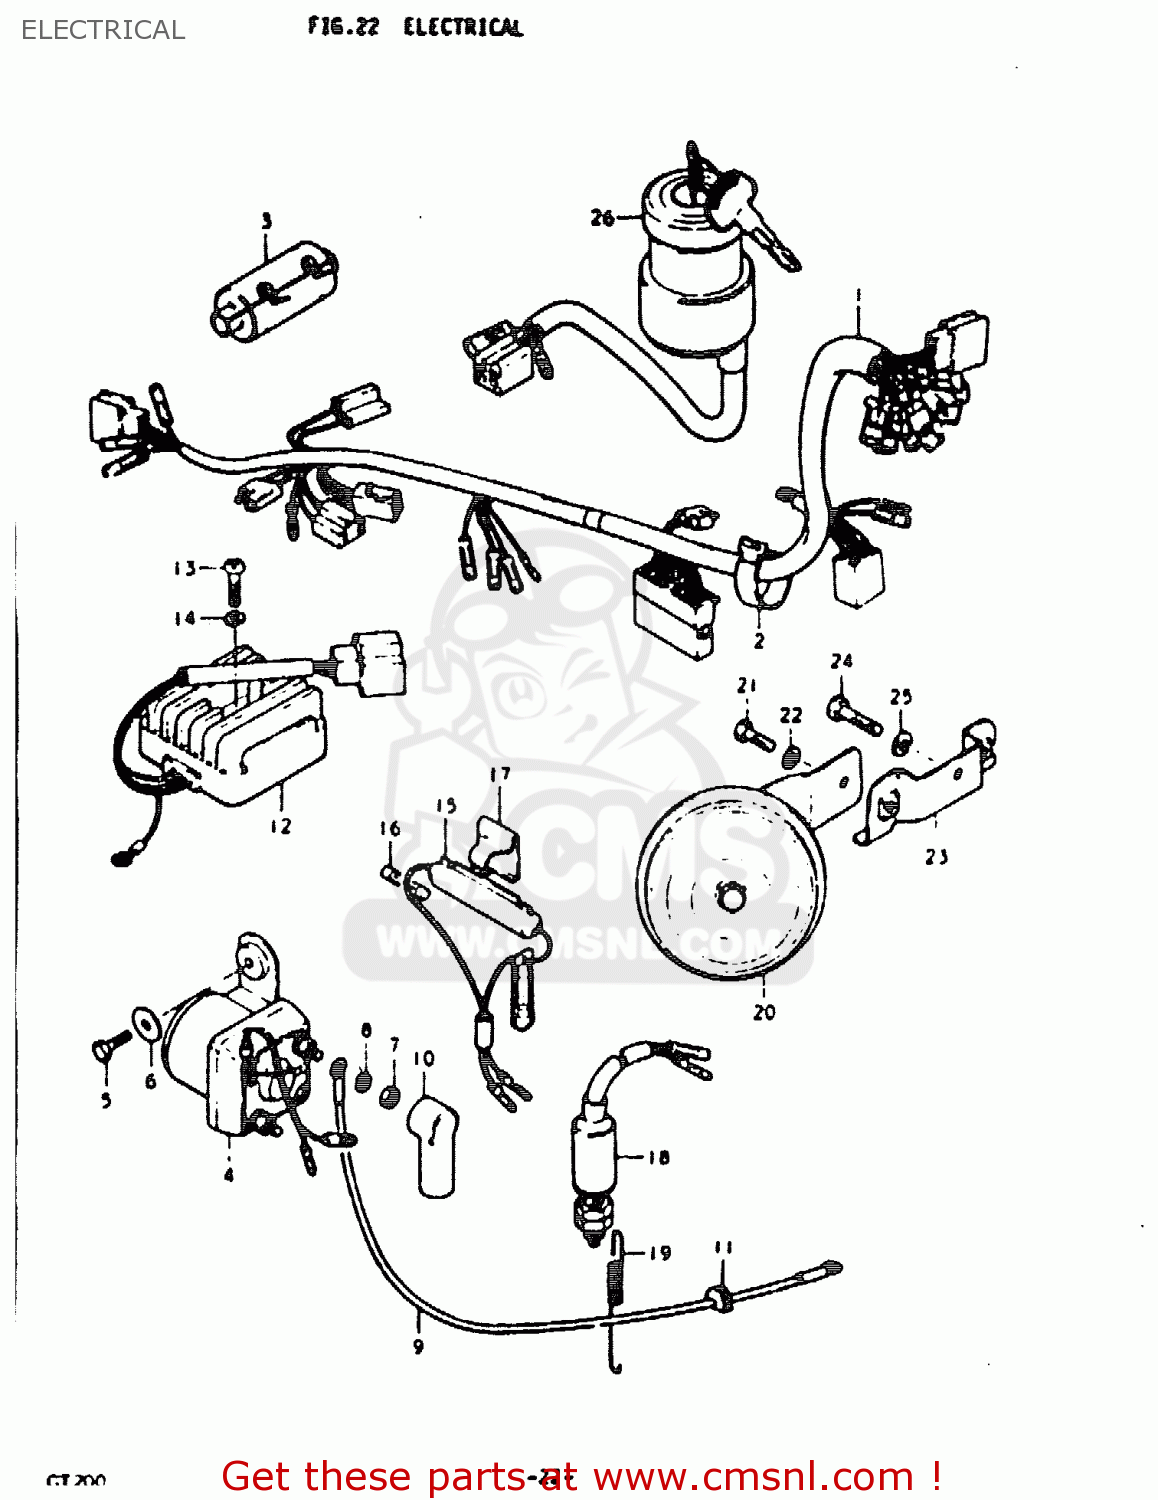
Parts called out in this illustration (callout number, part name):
1	WIRING HARNESS
2	CLAMP
3	BOOT,WIRING HARNESS
4	RELAY,STARTER SWITCH
5	BOLT, UPPER
6	WASHER
7	NUT 6MM
8	LOCK WASHER
9	WIRE,STARTER MOTOR LEAD
10	CAP,STARTER RELAY
11	GROMET
12	RECTIFIER ASSY,REGULATOR
13	SCREW
14	LOCK WASHER
15	BOX ASSEMBLY,FUSE
16	FUSE(15A)
17	HOLDER,FUSE CASE
18	SWITCH ASSEMBLY,STOP LAMP
19	SPRING
20	HORN
21	BOLT
22	WASHER
23	BRACKET
24	BOLT
25	WASHER
26	SWITCH ASSY, IGNITION
